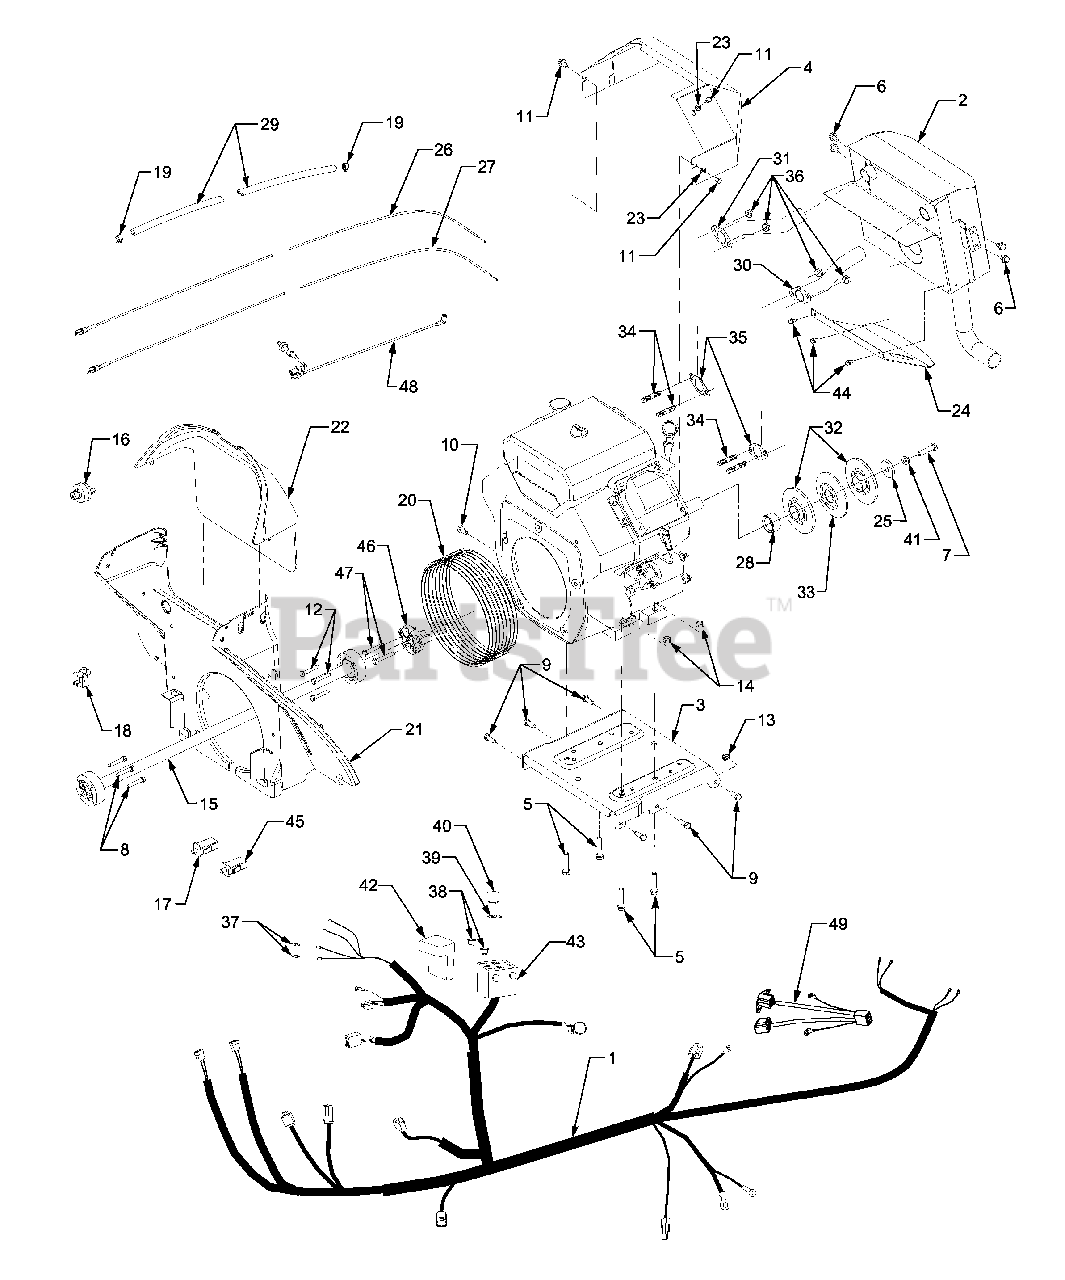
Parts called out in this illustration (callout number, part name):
1	Harness, Wire
1	Tie, Pushmount
1	Clip, Cable
2	Muffler Assembly
3	Plate, Engine Mounting
4	Shield, Muffler Heat
5	Screw, Hex Cap, 3/8-24 x 1.75 GR5
6	Screw, Hex Wash. Hd. Tapp 5/16-18 x .5
7	Screw, Hex Cap, 7/16-20 x 1.5 GR5
8	Screw, Hex Cap Lock 1/4-20 x 1.25 GR5
9	Screw, Hex Cap, 5/16-18 x .875 GR5
10	Screw, Hex Cap, M8 - 1.25 x 16MM GR5
11	Screw, Hex Cap, M6 - 1.0 x 10MM
12	Screw, Hex Cap, Lock 1/4-20 x 1.62 GR5
13	Nut, Hex Insert Lock, 5/16-18
14	Nut, Hex Lock, 3/8-24
15	Shaft, Drive, 27.125 Long
16	Switch, Key
17	Switch, Plunger (Reverse)
18	Switch, Snap Mount (Seat)
19	Clamp, Hose
20	Boot, Intake
21	Baffle, Lower Air
22	Baffle, Upper Air
23	Washer, Flat, .281 x .50 x .06
24	Shield, Lower Exhaust
25	Washer, Flat, .417 x 1.5 x .225
26	Cable, Throttle Control
27	Cable, Choke Control
28	Spacer, Crankshaft
29	Hose, Fuel Line
30	Pipe, Exhaust RH
31	Pipe, Exhaust LH
32	Pulley Half
33	Pulley, Center
34	Stud, M8 - 1.25 x 33MM
35	Gasket, Exhaust
36	Nut, Hex, M8 x 1.25
37	Bulb, Indicator
38	Fuse, 25 Amp
39	Gasket, Silicone
40	Relay, PTO
41	Washer, Lock, 7/16
42	Cover, Fuse Box
43	Box, Fuse
44	Screw, Hex Wash. Hd. Tapp, #12-24 x .38
45	Switch, Plunger (Brake)
46	Adapter, Drive Shaft
47	Screw, Hex Flange, M10 x 1.5 x 90
48	Hose, Vacuum
